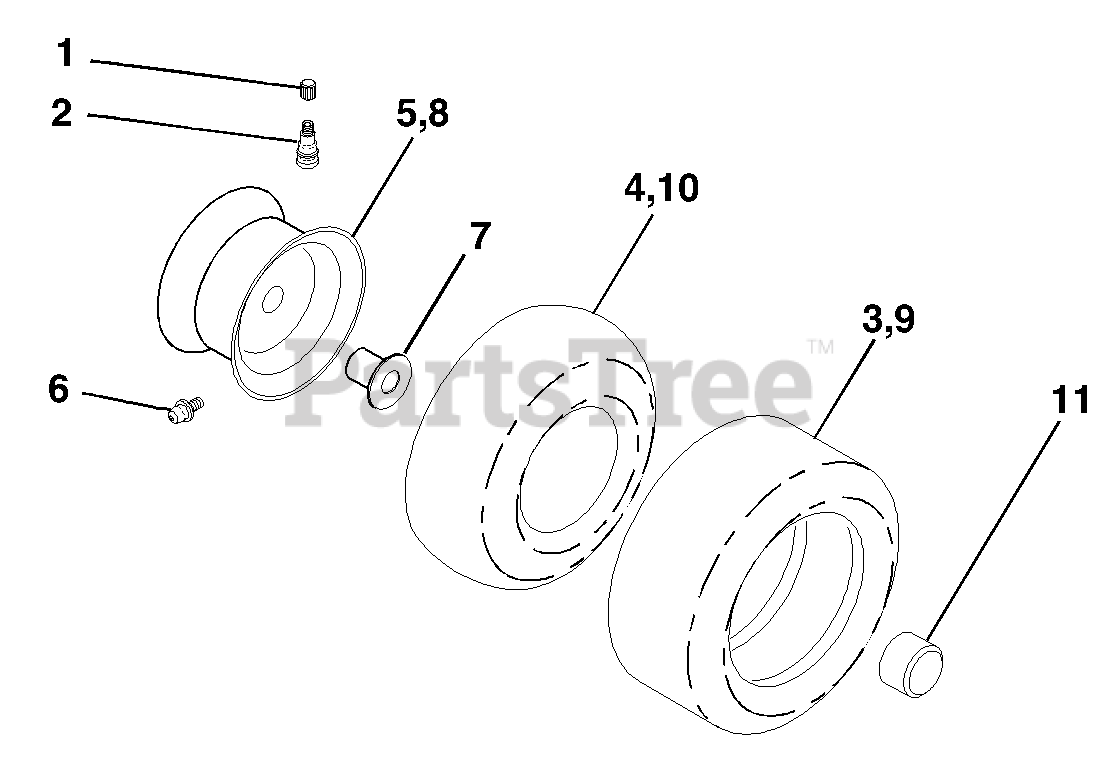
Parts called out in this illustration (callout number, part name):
1	Cap Valve Tire
2	Stem Valve
3	Tire Front
4	Tube Front
5	Rim Asm 8" front
6	Fitting Grease
7	Bearing Flange
8	Rim Asm 12" rear
9	Tire R 23 x 8.5-12 C Service
10	Tube Rear
11	Cap Axle Blk 1 50 X 1 00
